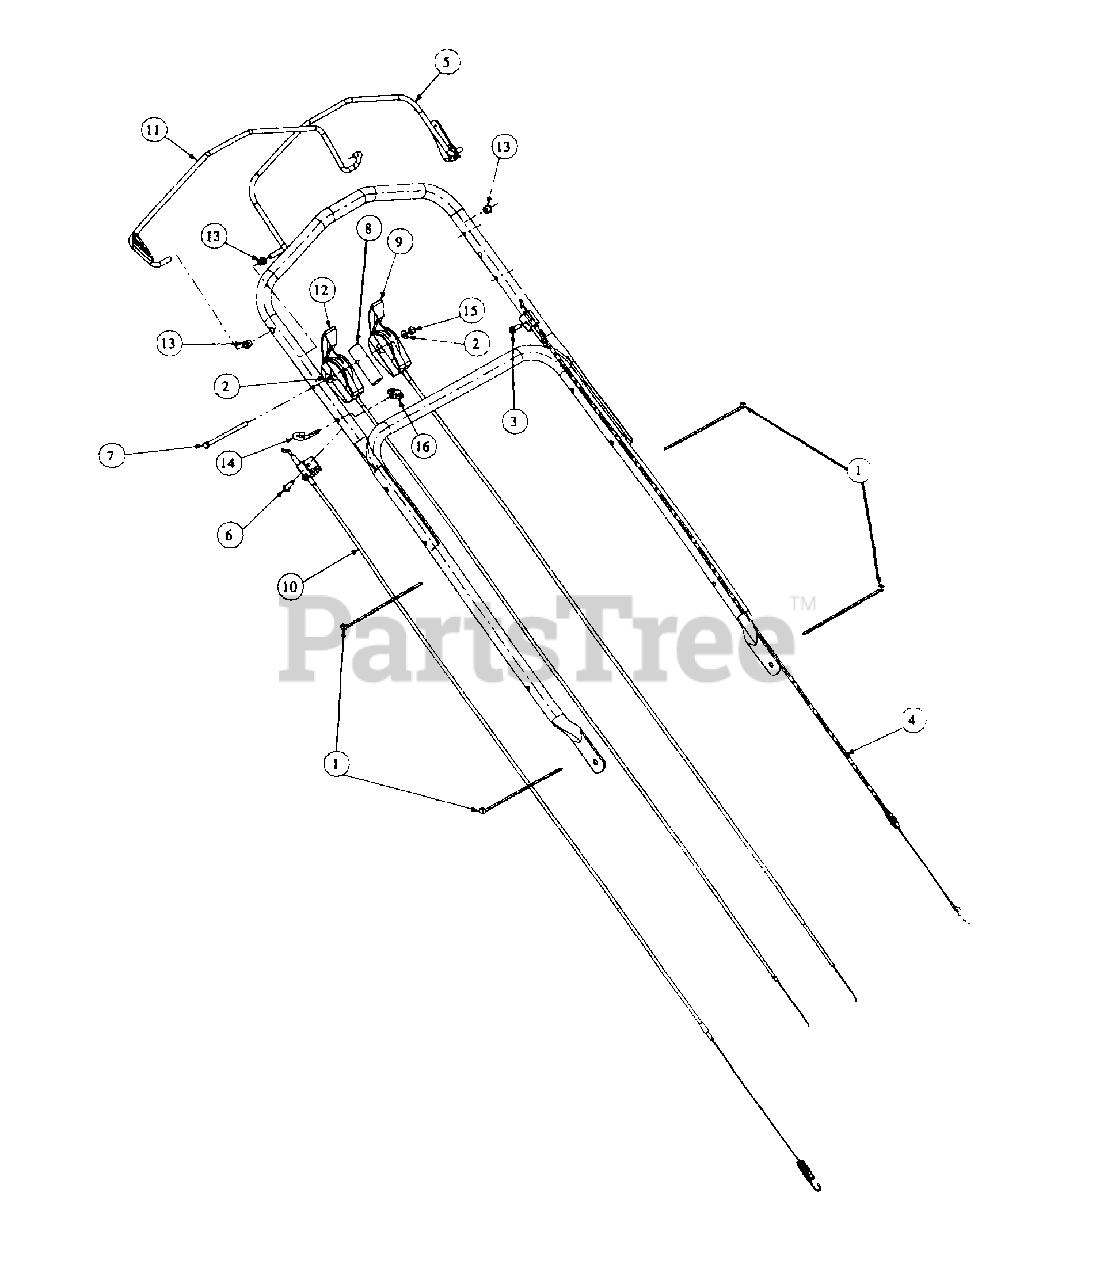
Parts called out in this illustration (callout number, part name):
1	CBL: TIE:3/16 X .05 X 7.4
2	FLAT WASHER 1/4 X .630 X .0515
3	SCR:TT:1/4-20:0.750:HX INDWSH
4	CBL: CONT: 43" LG. BRIGGS
5	LVR:CONT:COMMERCIAL W/0 BBC
6	SCR:TT:1/4-20:1.000:HX INDWSH
7	HHCS:1/4-20 X 3.75: GR5
8	SPCR:7/8 DIA. X 2.875
9	CONT:SHFT:3 SPEED W/CABLE
10	CABLE: CLUTCH: S/P ADJ.
11	BAIL: CLUTCH: TRANS,COMM WBM
12	CONT:THROT:W/CABLE, BRIGGS
13	BUSH: .3125 DIA., SNAP
14	BOLT:EYE:1/4-20:BENT ROPE GDE
15	NUT:HX:1/4-20:GRC:LOCK
16	WING NUT
